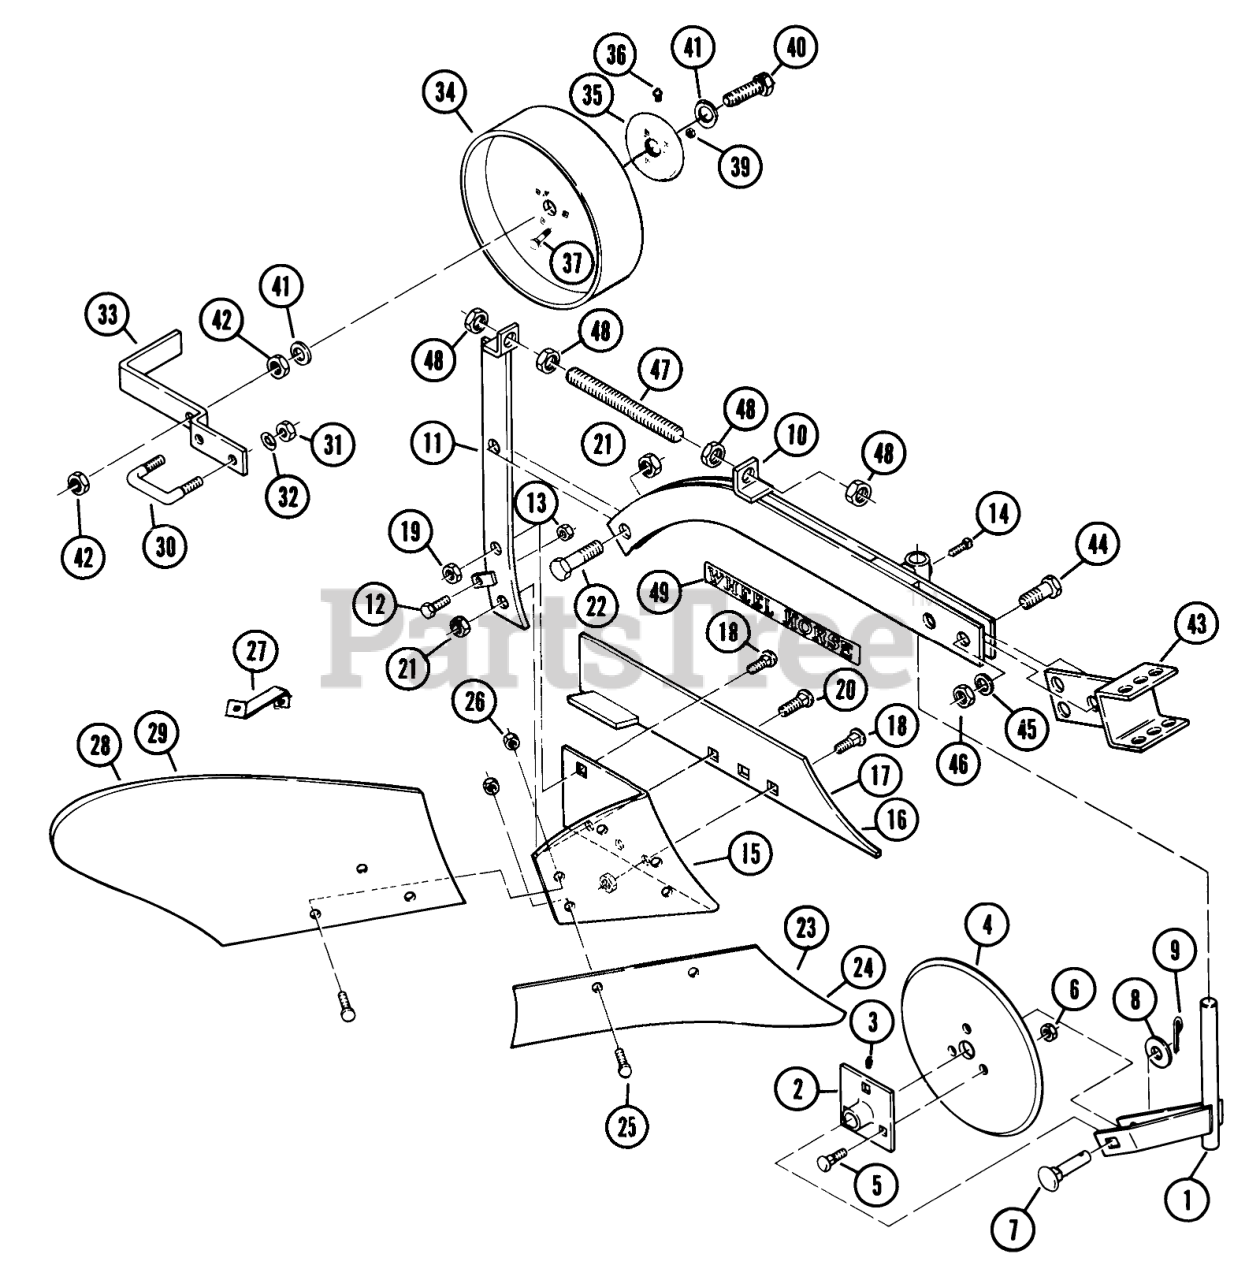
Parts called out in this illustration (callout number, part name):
1	Fork Assembly
2	Hub Assembly
3	Grease Fitting
4	Coulter Blade
5	Bolt
6	Nut
7	BOLT-CARR BLANK
8	Washer 5/8 U.S.
9	Cotter Pin
10	Beam Assembly
11	Standard Assembly
12	H H C S
13	Eslok Nut
14	Screw-Set
16	8" Landslide
17	12" Landslide
18	Plow Bolt 3/8-16 x 1
19	Sq. Nut-3/8-16
20	Plow Bolt 1/2-13 x 2
21	Nut, 1/2-13
22	CARRIAGE BOLT -4
23	8" Share
24	12" Share
25	Plow Bolt 7/16-14 x 1
26	Nut
27	Brace
28	8" Mold Board
29	12" Mold Board
30	Special "U" Bolt
32	Lockwasher
33	Gage Wheel Brace
34	Gage Wheel Assembly
35	Hub Assembly
36	Grease Fitting
37	Bolt
37	WASHER 5/16 SAE
39	Nut
40	Hex Bolt 5/8-11 x 4 1/2
41	WASHER
43	Yoke Assembly
44	Bolt
45	Lockwasher
48	Jam Nut 5/8-11
49	DECAL-WHEEL HORSE
